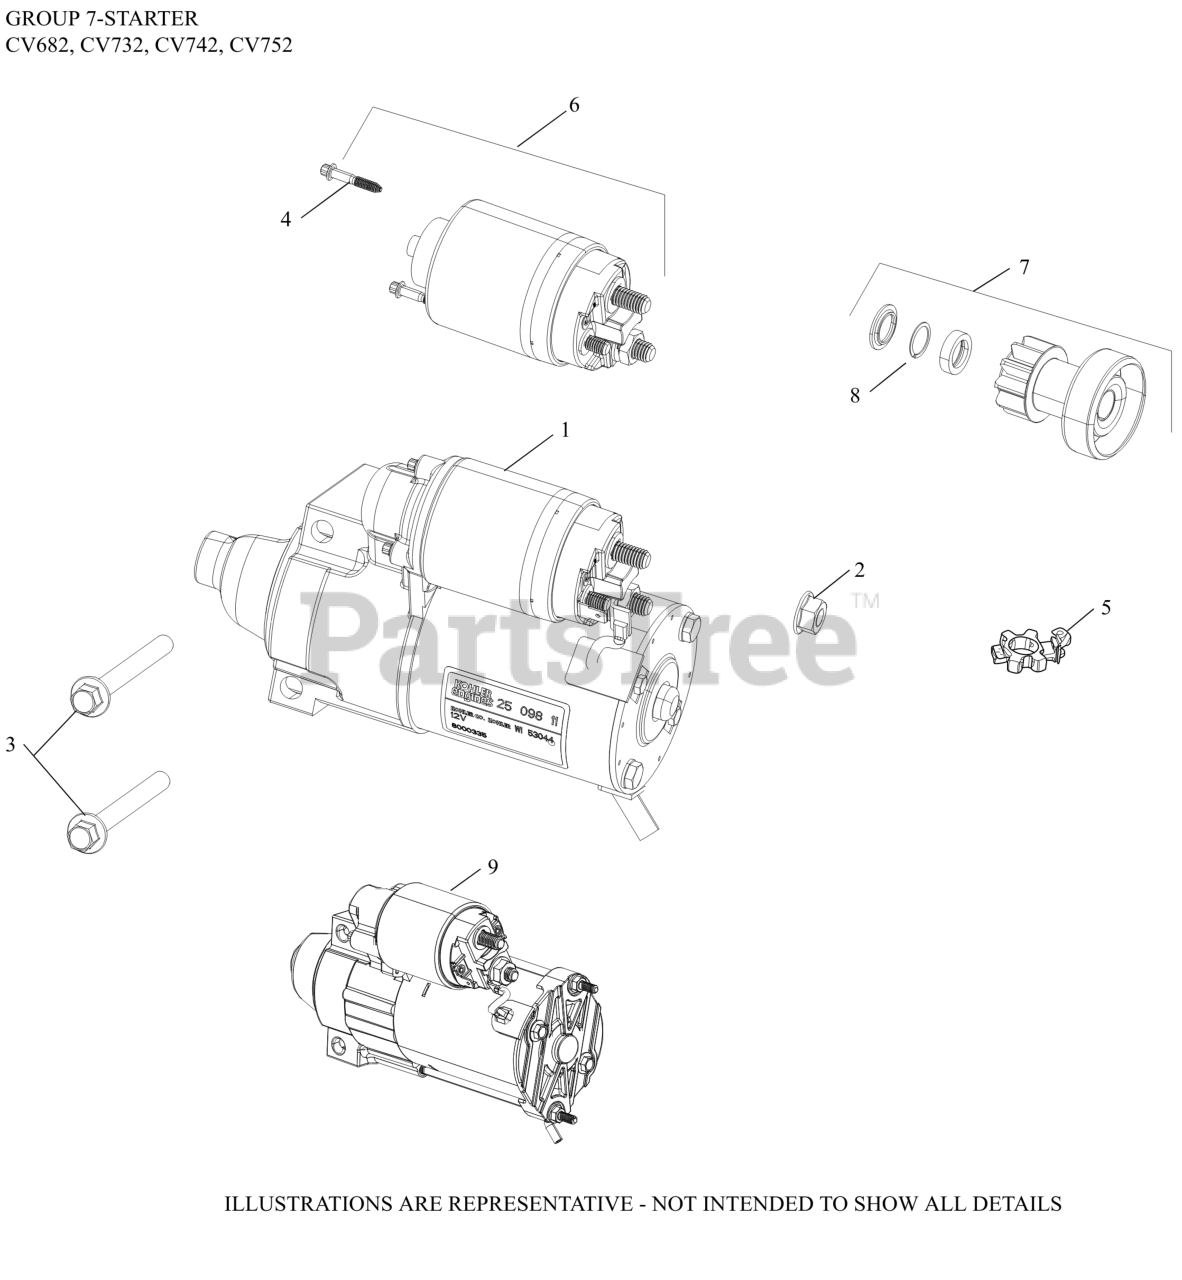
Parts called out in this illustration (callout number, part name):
1	STARTER, SOLENOID SHIFT-(#2509824S)
2	NUT, FLG M8X1.25
3	SCREW, FLG M8X1.25X80
